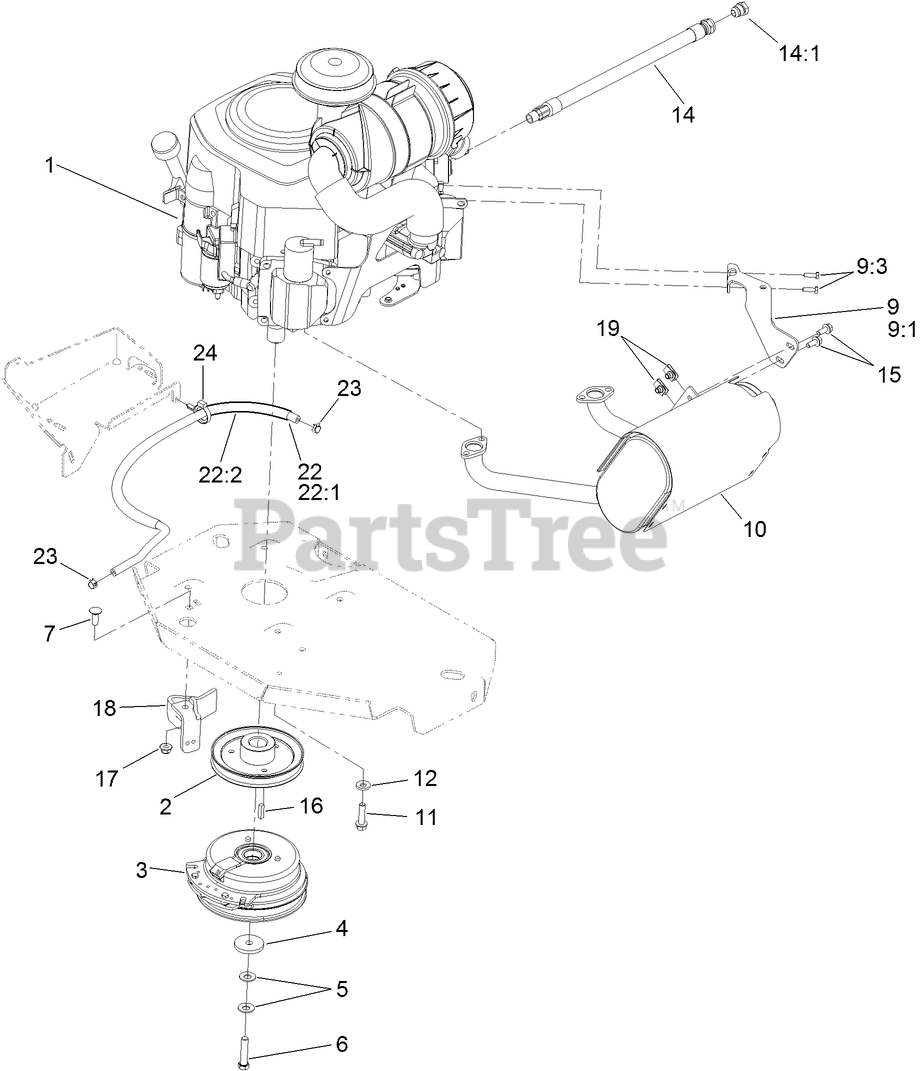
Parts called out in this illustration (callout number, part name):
2	SHEAVE
3	CLUTCH KIT
4	WASHER-CLUTCH
5	WASHER-SPRING
6	SCREW-HH W/LOCTITE
7	SCREW-CARR
9	MUFFLER BRACKET KIT
9:1	BRACKET-MUFFLER
9:3	SCREW-HH
10	MUFFLER
11	SCREW-HWH
12	WASHER-BELLEVILLE
14	OIL DRAIN HOSE ASM
15	SCREW-HHF
17	NUT-HF, NI
18	CLUTCH-ANCHOR
19	NUT-U
22	FUEL LINE ASM
22:1	HOSE-FUEL
22:2	SLEEVE-THERMAL
23	CLAMP-HOSE
24	CLAMP-HOSE
